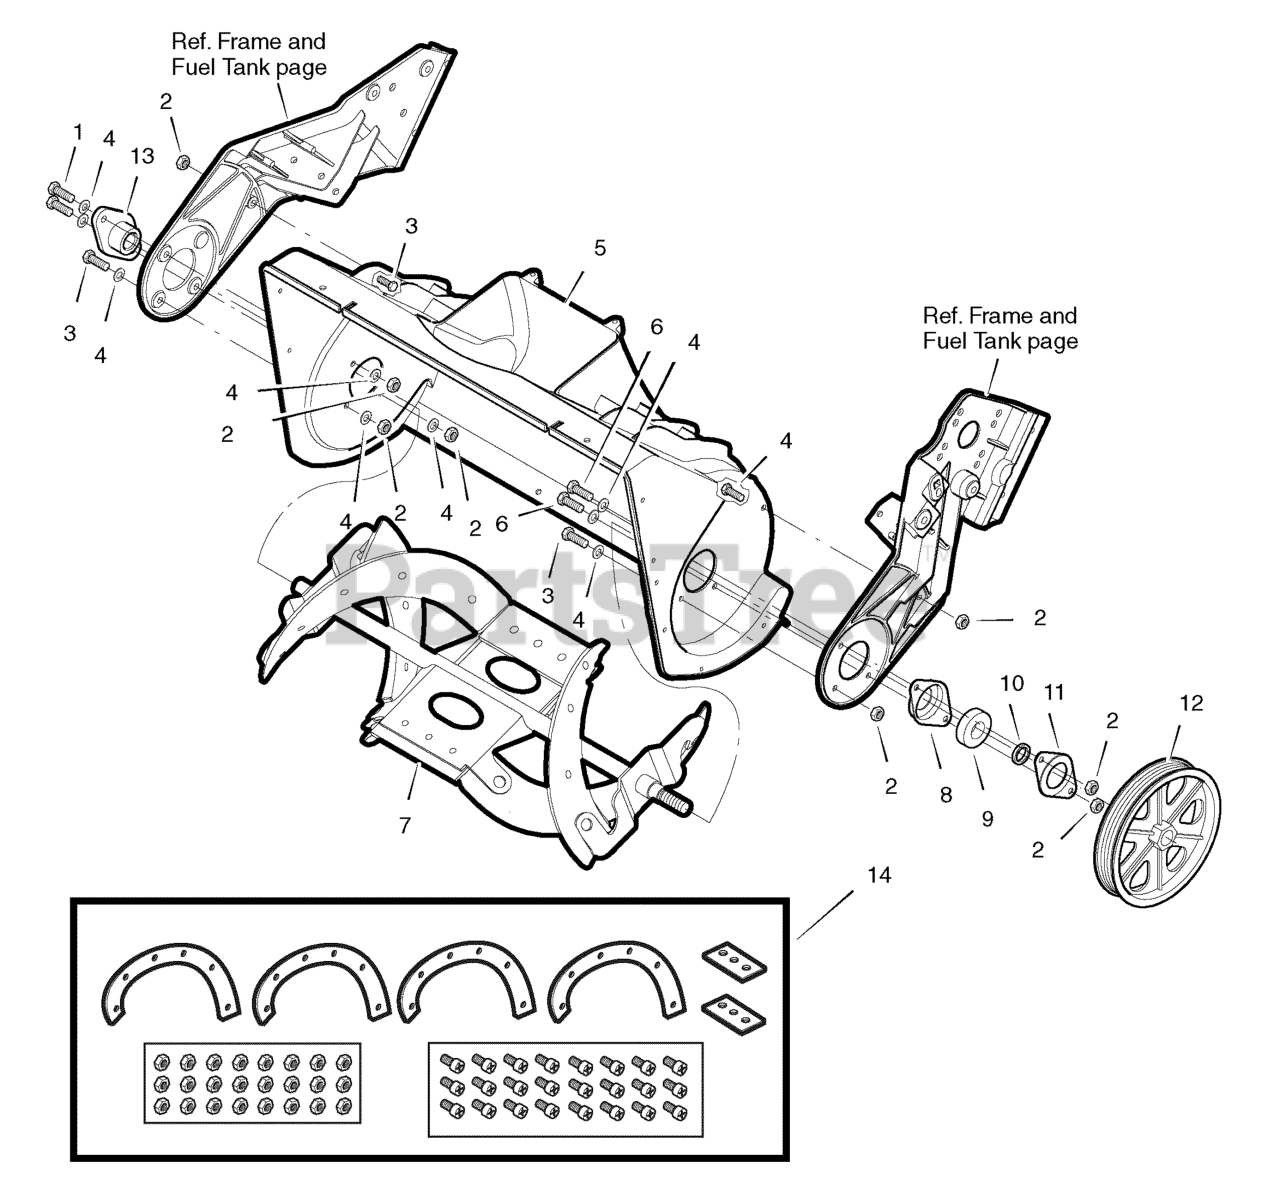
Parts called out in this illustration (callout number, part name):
1	Screw 1/4-20 x 1.00
2	Nut, Hex 1/4-20
3	Screw, 1/4-20 x .75
4	Washer, Flat
5	Housing Assembly, Auger
6	Screw, 1/4-20 x .63
7	Auger Assembly, 22"
8	Retainer, Bearing
9	Bearing
10	Sleeve, Spacer
11	Plate, Bearing Retainer
12	Pulley, Auger Drive V6
13	Bearing, Flange
14	KIT, Auger Flighting Replacement
